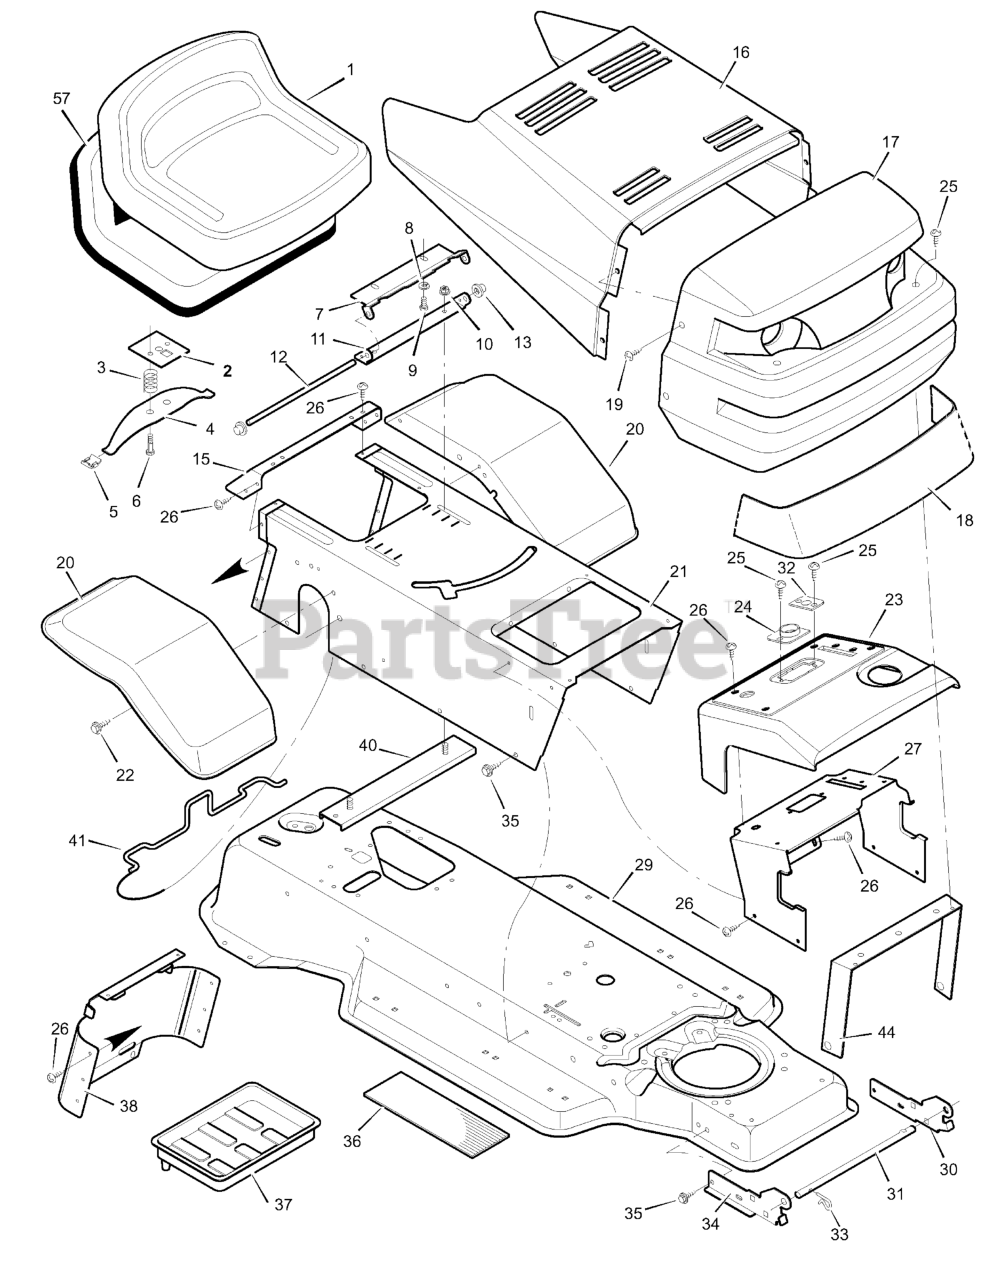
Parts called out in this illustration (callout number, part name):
2	Plate Assembly, Switch
3	Spring, Compression
4	Spring, Seat
5	Glide, Spring
6	Bolt, Shoulder
7	Support, Seat
8	Lockwasher
9	Bolt, Hex
10	Locknut, Flange
11	Bracket, Pivot
12	Rod, Pivot
13	Cap, Push On
15	Fender, Apron
17	Grille Assembly
21	Console Assembly
23	Dash Panel
24	Bearing, Steering
26	Screw
27	Support, Dash
29	Frame Assembly
30	Bracket, Left Grille
31	Rod, Pivot
32	Bearing
33	Pin, Hair
34	Bracket, Right Grille
37	Tray, Battery
38	Cap, Console
39	Bolt
40	Channel Assembly
41	Clamp, Battery
44	Brace, Grille
57	Pan, Seat (with foam)
